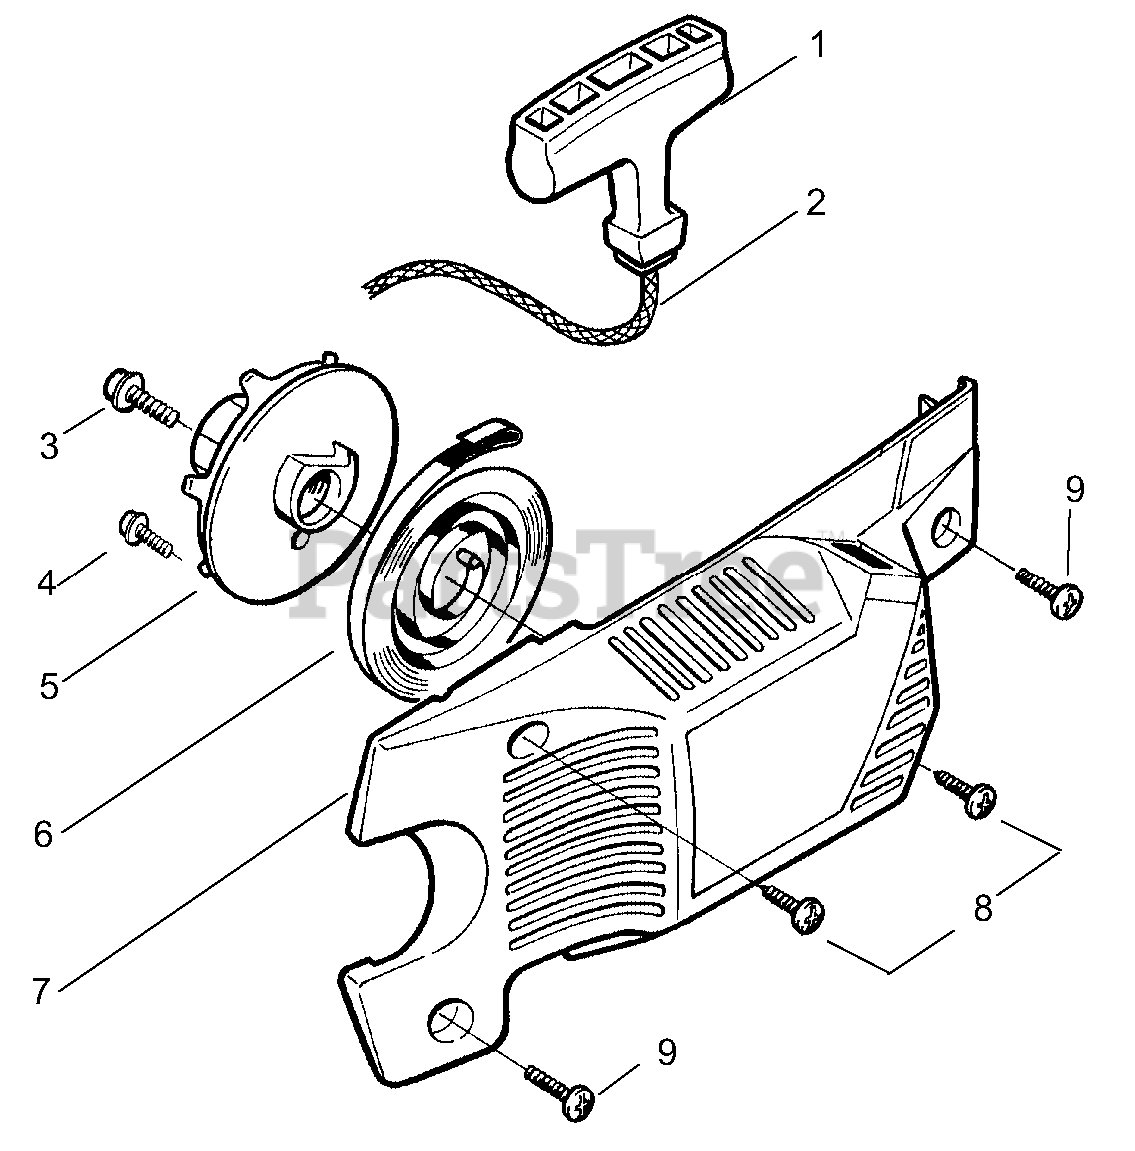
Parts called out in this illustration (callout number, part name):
1	STARTER HANDLE
5	PULLEY 36/41
6	RETURN SPRING
7	FAN HOUSING ASSEMBLY
8	SCREW,STRTR CVR 36/41
